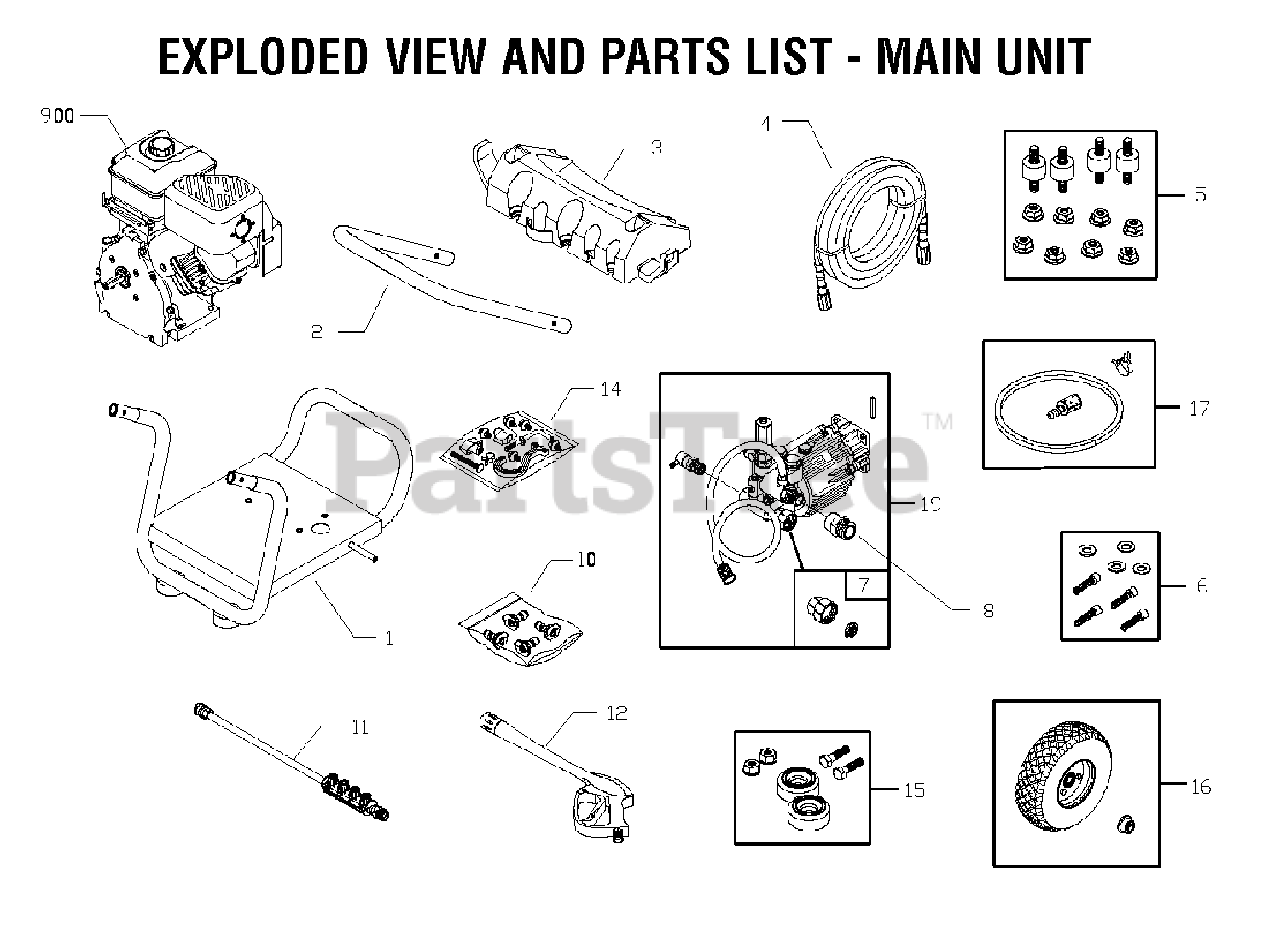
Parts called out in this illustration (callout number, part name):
3	BILLBOARD
5	KIT, Engine Mounting Hardware
6	KIT, Pump Mounting Hardware
7	KIT, Inlet, Hose, Garden
8	CONNECTOR, Garden Hose
10	KIT, Nozzle
11	EXTENSION, QC w/Nozzle Holder
14	KIT, Handle Fasteners
15	KIT, Vibration Mount
16	KIT, Wheel
17	KIT, Chem Hose & Filter
19	ASSY, Pump
